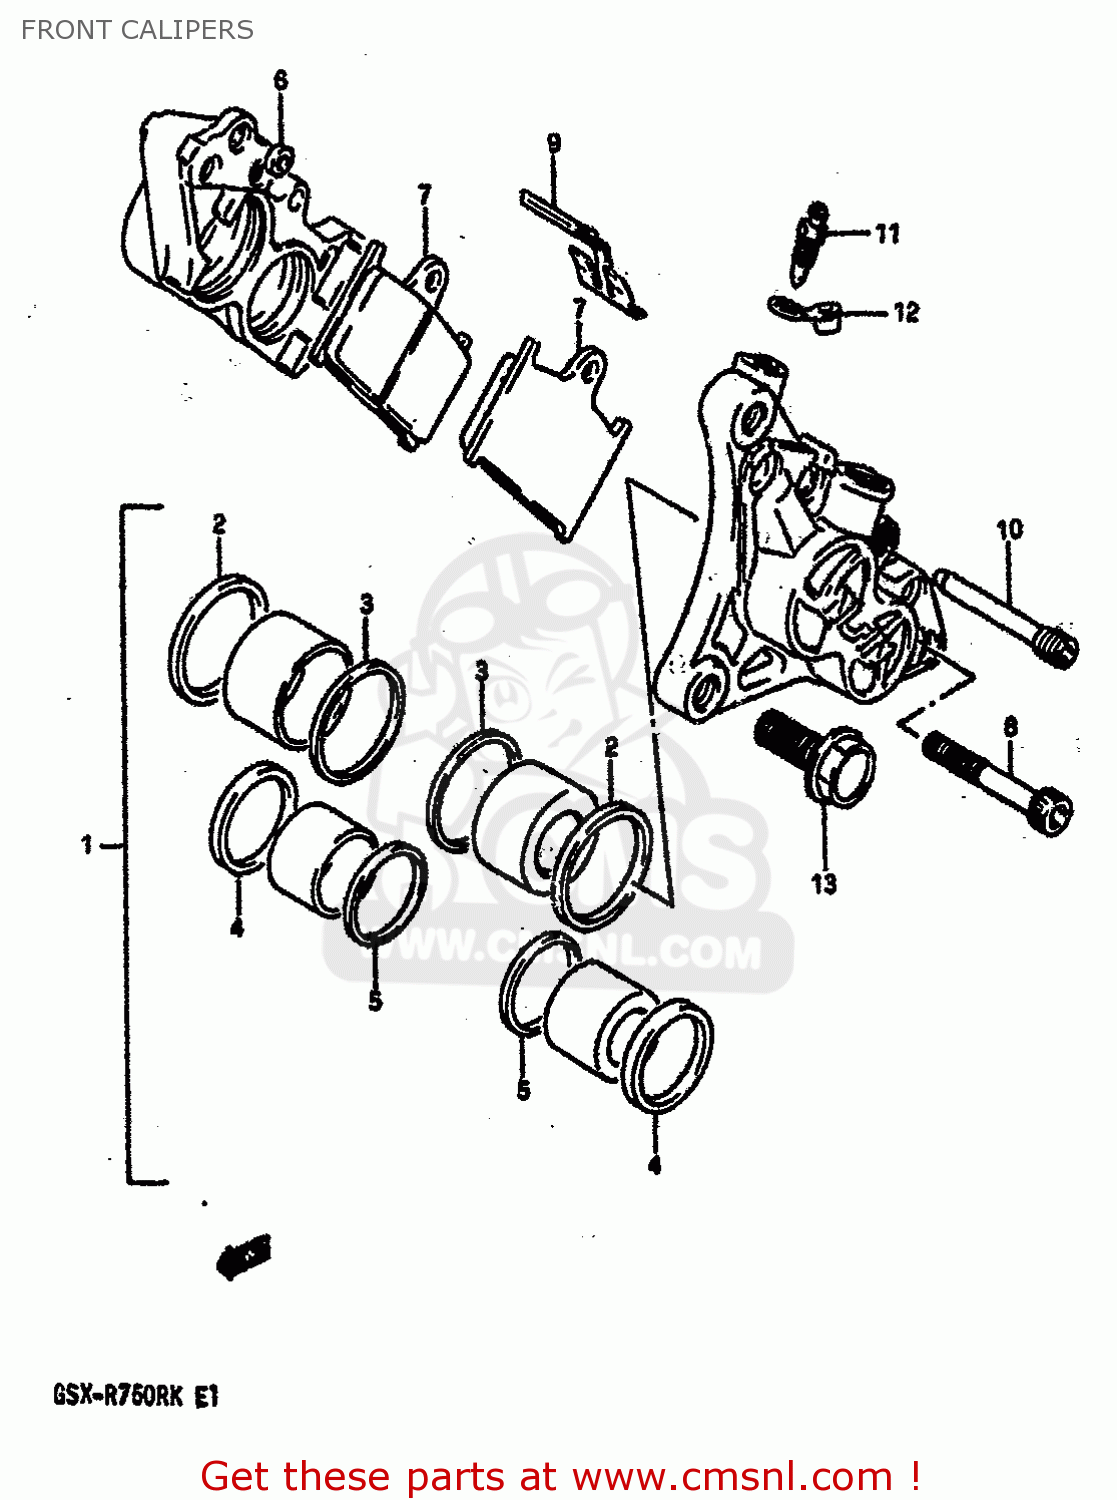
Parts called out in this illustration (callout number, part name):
1	PISTON SET
2	SEAL,PISTON
3	BOOT,PISTON
4	SEAL,PISTON
5	SEAL
6	SEAL
7	PAD
8	BOLT
9	SPRING
10	PIN,HOLDER
11	BLEEDER
12	CAP,BLEEDER
13	BOLT 10X30
